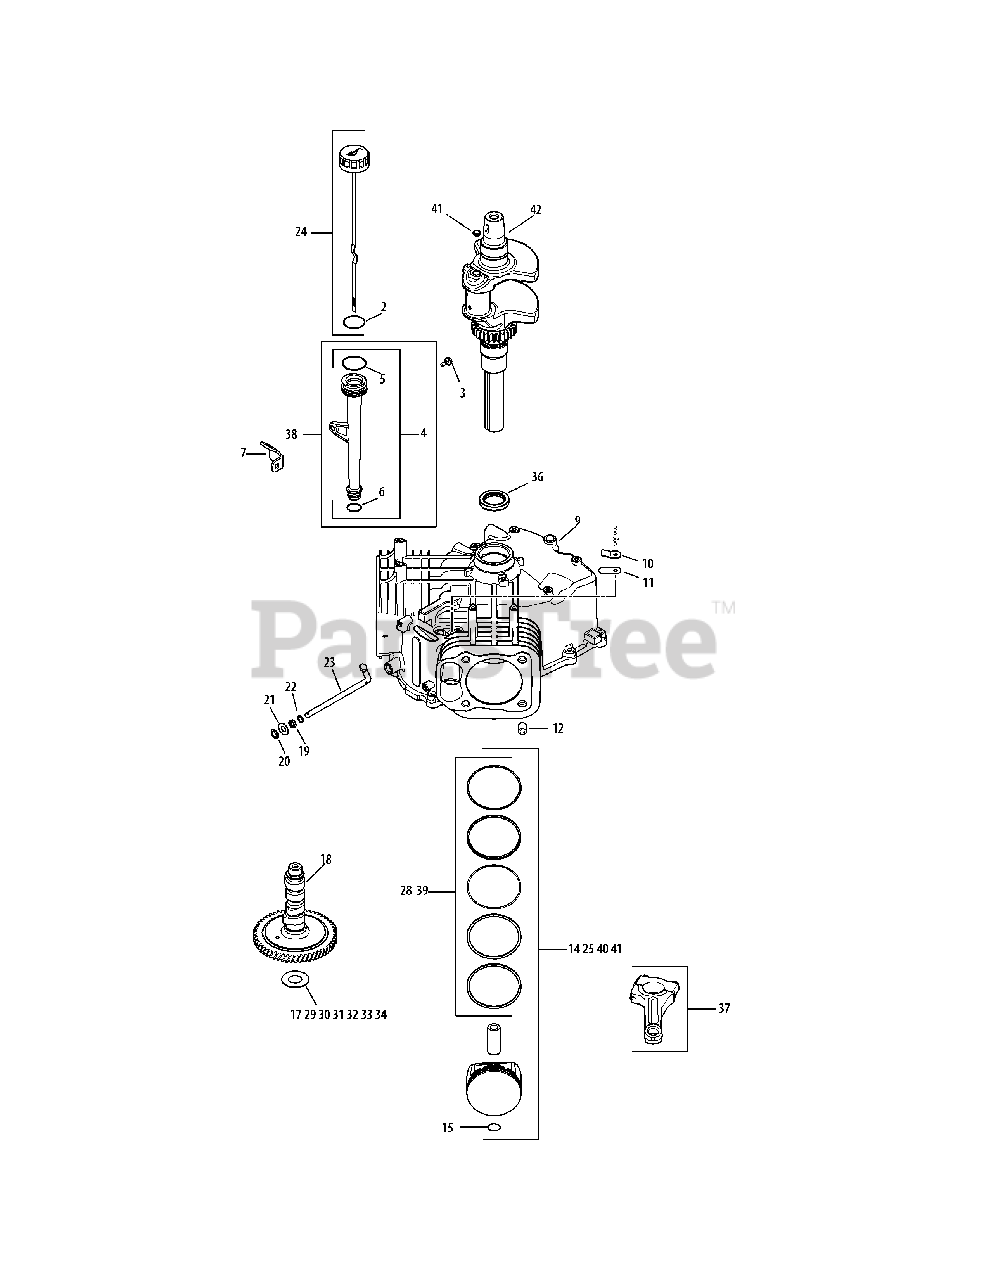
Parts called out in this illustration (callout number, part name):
3	Flg. Thd. Frm. Screw, M5 X 0.8 X 13
4	Tube
5	Ring
6	Ring
7	Oil Fill Tube Bracket
9	Block
10	Breather Reed Retainer
11	Breather Reed
14	Piston Kit w/ Ring Set (Inc. 15, 16)
15	Piston Pin Retainer
17	Camshaft Shim (White .028")
18	Camshaft Kit (Inc. KH-25-357-14-S)
19	Governor Cross Shaft Seal
20	Ring Retainer
21	Flat Washer, 9 Mm
22	Flat Washer, 11/32
23	Governor Cross Shaft
24	Dipstick Assembly (Inc. 2)
25	Piston Kit w/ Ring Set (0.25) 83mm
28	Ring Set (.25)
29	Camshaft Shim (Blue .03")
30	Camshaft Shim (Red .032")
31	Camshaft Shim (Yellow .034")
32	Camshaft Shim (Green .036")
33	Camshaft Shim (Gray .038")
34	Camshaft Shim (Black .04")
36	Oil Seal (Helix Lip)
37	Connecting Rod (Std)
38	Tube Assembly (Inc. 4-6)
39	Ring Set (Std)
40	Kit, Piston w/Ring
42	Crankshaft (Includes 2)
